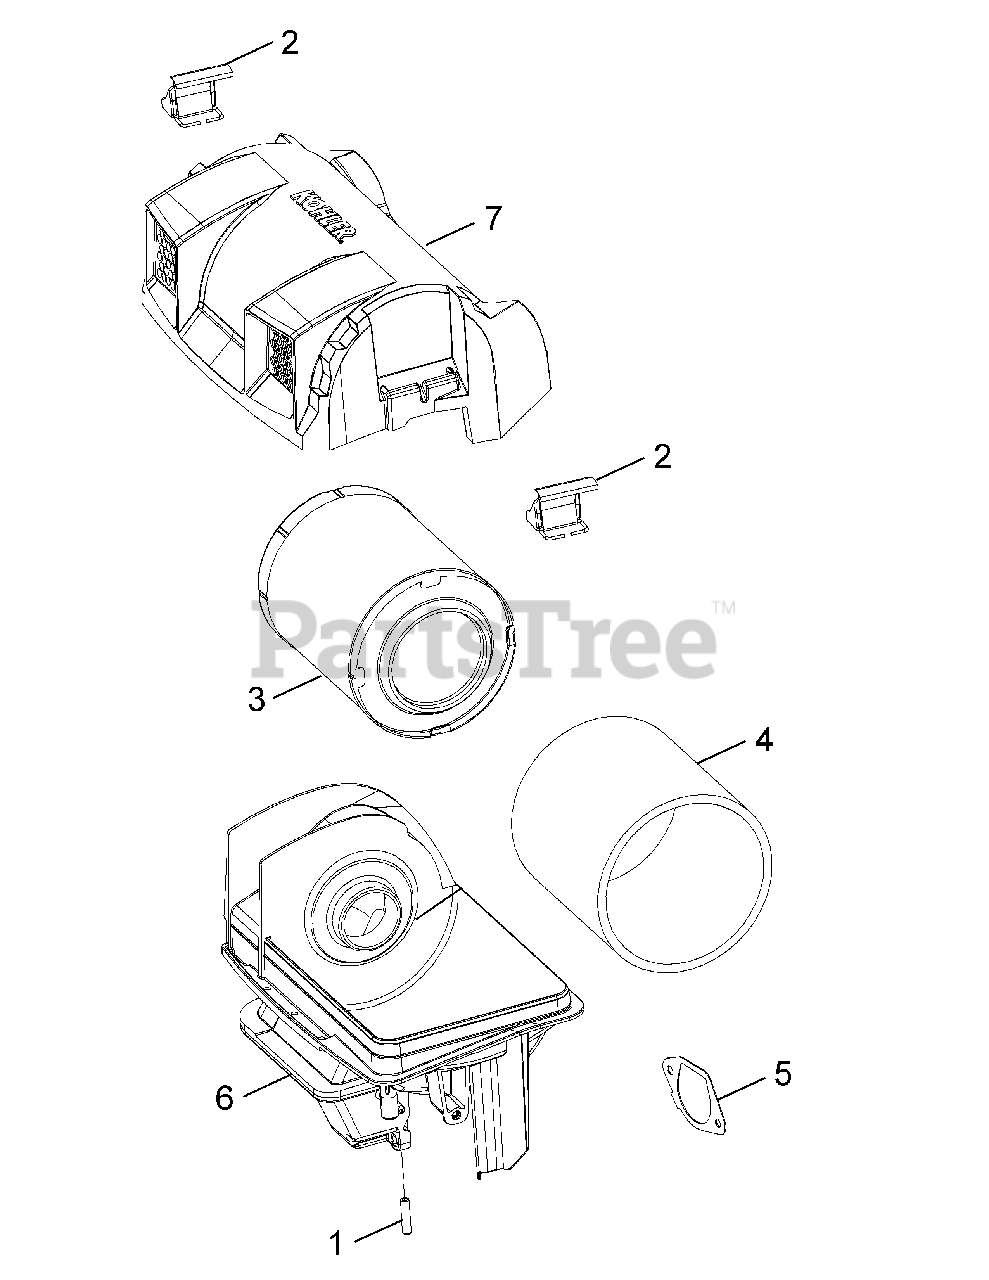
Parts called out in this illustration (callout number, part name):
2	Air Cleaner Cover Latch Assembly
3	Air Filter Element
4	Pre-Cleaner Element
5	Air Cleaner Base Gasket
6	Air Cleaner Base Assembly
7	Air Cleaner Cover
